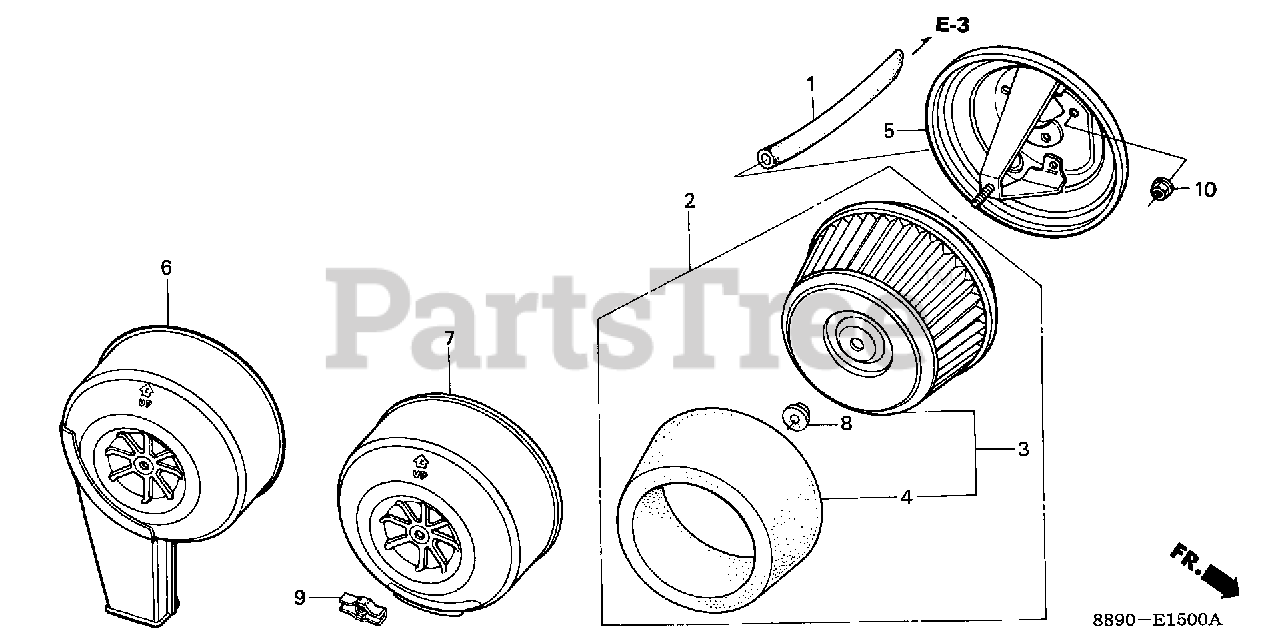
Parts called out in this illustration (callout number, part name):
1	TUBE, BREATHER
2	ELEMENT, AIR CLEANER
3	ELEMENT, AIR CLEANER
4	FILTER (OUTER) (NOT AVAILABLE)
5	HOUSING, AIR CLEANER
6	COVER, AIR CLEANER
7	COVER, AIR CLEANER
8	GROMMET, AIR CLEANER
9	NUT, AIR CLEANER COVER (DACRO COATING)
10	NUT, FLANGE (6MM)
